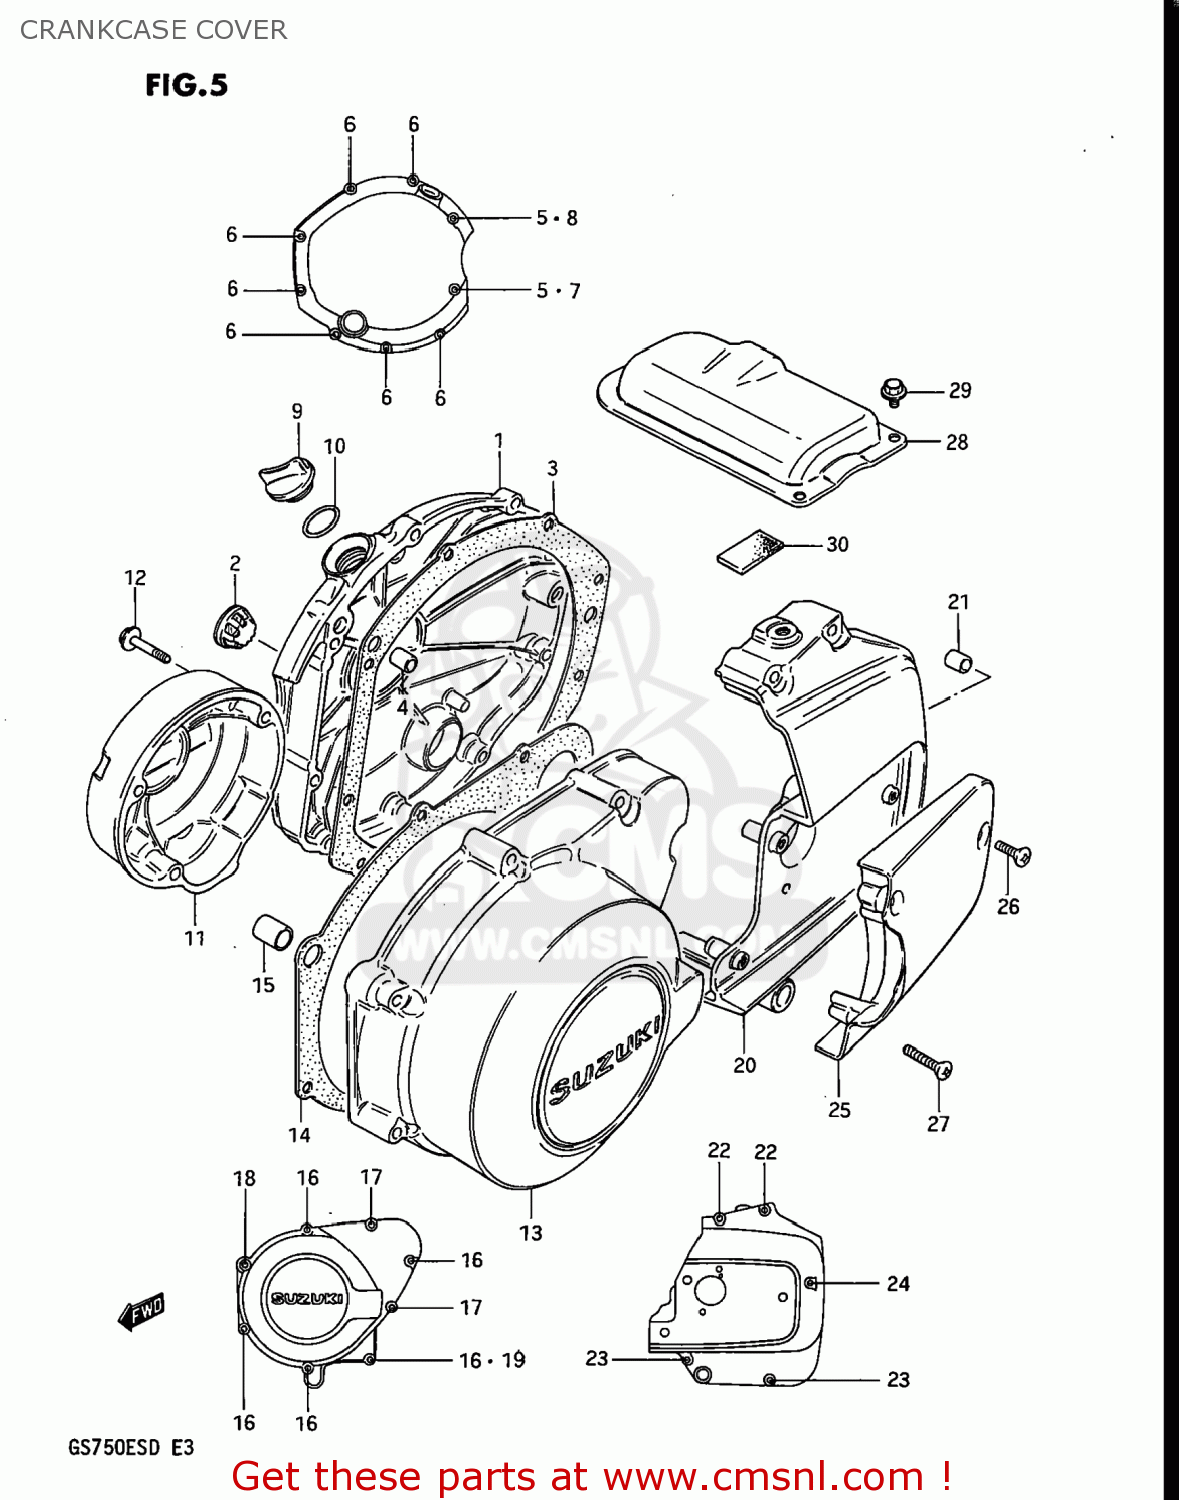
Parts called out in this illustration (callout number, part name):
1	COVER,CLUTCH
2	LENS,OIL LEVEL CHECK
3	GASKET,CLUTCH COVER (MCA)
4	PIN
5	WASHER
6	BOLT
7	BOLT (6X30)
8	BOLT (6X35)
9	PLUG(20X10)
10	O RING(D:3.1,ID:16.8)
11	COVER,CONTACT BRAKER
12	BOLT (5X30)
13	COVER,MAGNETO
14	GASKET,MAGNETO COVER (MCA)
15	PIN (11X20)(SUS)
16	BOLT (6X35)
17	BOLT (6X40)
18	BOLT
19	WASHER
20	COVER,ENGINE SPROCKET
21	PIN
22	BOLT (6X40)
23	BOLT (6X50)
24	BOLT (6X70)
25	CAP,CLUTCH RELEASE ADJUST
26	SCREW
27	SCREW
28	COVER,STARTER MOTOR
29	BOLT (5X8)
30	DAMPER,STARTER MOTOR CLUTCH
